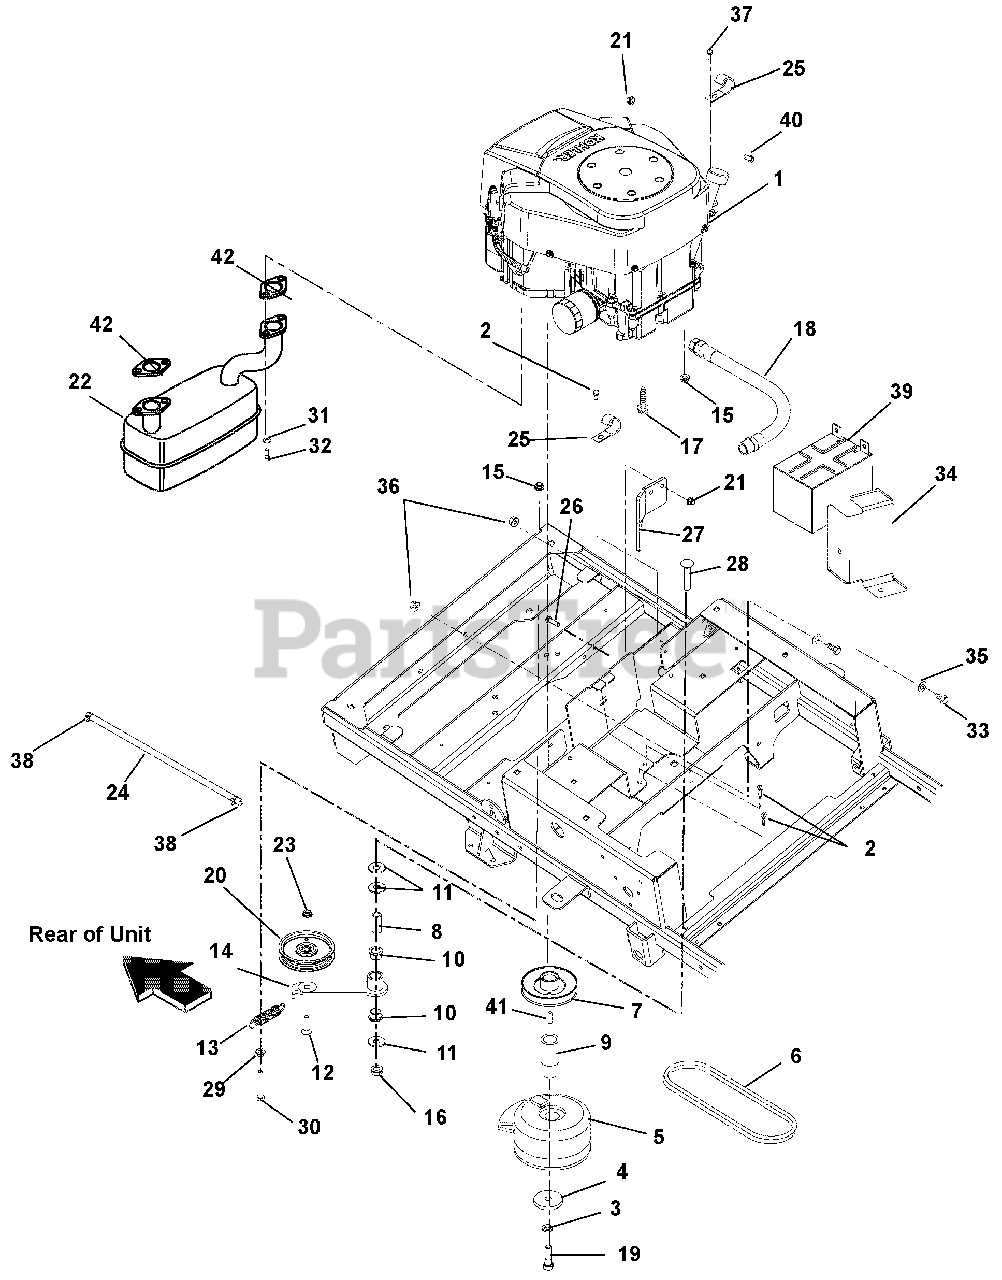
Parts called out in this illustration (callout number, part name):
1	ENGINE, KOHLER TWIN 20 HP
1	ENGINE, KOHLER TWIN - 22HP
1	ENGINE, KOHLER TWIN - 24HP
2	@SCR-TAP .25-20X.37 HWH YWZ TR
3	@WSHR-LK .44X.109 REG YWZC
4	WSHR-FL-STL .469X2.00X.25 YWZC
5	CLUTCH,105FTLB MONOPOLE 6.83"
5	CLUTCH,105FTLB MONOPOLE 6.12"
6	V-BELT, HA-WRAPPED
7	PULLEY, V-1" ID X 4.50" OD
8	BSHG-SLV .500X.750X1.560
9	EXT-CRANKSHAFT LOWER
10	BSHG-FLG 0.75X0.875X.625X1.125
11	@WSHR-FL-STL.563X1.38X.109YWZC
12	@BLT-RDHDSQNK .38-16X1.50 G5YZ
13	SG-TENS .105X.812X3.88 WLD 15
14	WMT, GROUND DRIVE IDLER ARM
15	@NUT-LK-NYL-FLG .38-16 YWZC
16	@NUT-LK-TOP-FLG .50-13 YWZC
17	@SCR-TAP .38-16X1.00 HWH TR YZ
18	OIL DRAIN HOSE
19	BLT-HEX .44-20X4.50 GR8 YWZC
20	ASM, 4" IDLER (.75 WIDE)
21	@NUT-LK-NYL-FLG .31-18 YWZC
22	MUFFLER, KOHLER TWIN COURAGE
23	@NUT-LK-TOP-FLG .38-16 YWZC
24	HOSE, .25 LOW-PERM BULK GAS
25	J-CLAMP
26	@BLT-HEX .31-18X1.00 GR5 YWZC
27	CLUTCH STOP
28	@BLT-RDHDSQNK .50-13X2.50 G5YZ
29	@NUT-SPNLK-FLG .375-16 YWZC
30	@BLT-HEX .38-16X2.50 GR5 YWZC
31	@WSHR-LK .31X.078 REG YWZC
32	SCR-CAP .31-18X.75 S/HD
33	@BLT-HEX .25-20X.75 GR5 YWZC
34	BRKT, BATTERY HOLDER
35	@WSHR-FL-STL.281X.62X.065 YWZC
36	NUT-KEPS .250-20
37	@BLT-HEX .38-16X.75 GR5 YWZC
38	CLAMP, FUEL LINE
39	BATTERY, 12V 12A-190CCA
40	BLT-SERHFWH .312-18X.50 YWZC
41	KEY-STR .25X2.0X.25
42	GASKET, MUFFLER COURAGE TWIN
